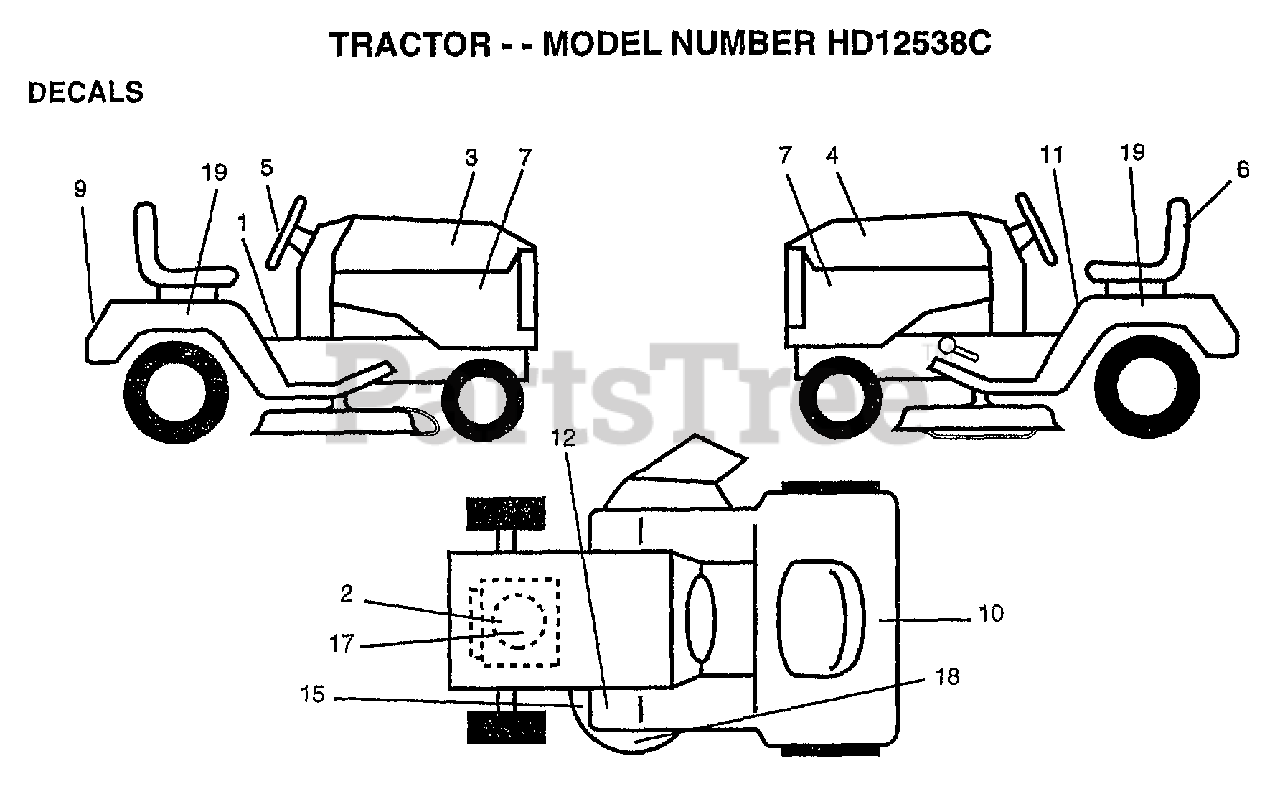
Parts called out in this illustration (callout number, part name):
2	DECAL, HP ENGINE
3	"DECAL HOOD,RH"
4	DECAL HOOD LH
5	"DECAL INS,STRG WH"
6	"DECAL SEAT,REPLCM"
7	"DECAL PENL,SIDE"
9	DECAL-FENDER
10	DECAL.BATRY.3-3908
11	"DECAL FENDER,DANG"
12	DECAL CLUT/BRAKE
15	DECAL
17	"DECAL ENGINE,REPL"
18	"DECAL MOWER,HOME"
19	"DECAL FENDER,5 SP"
